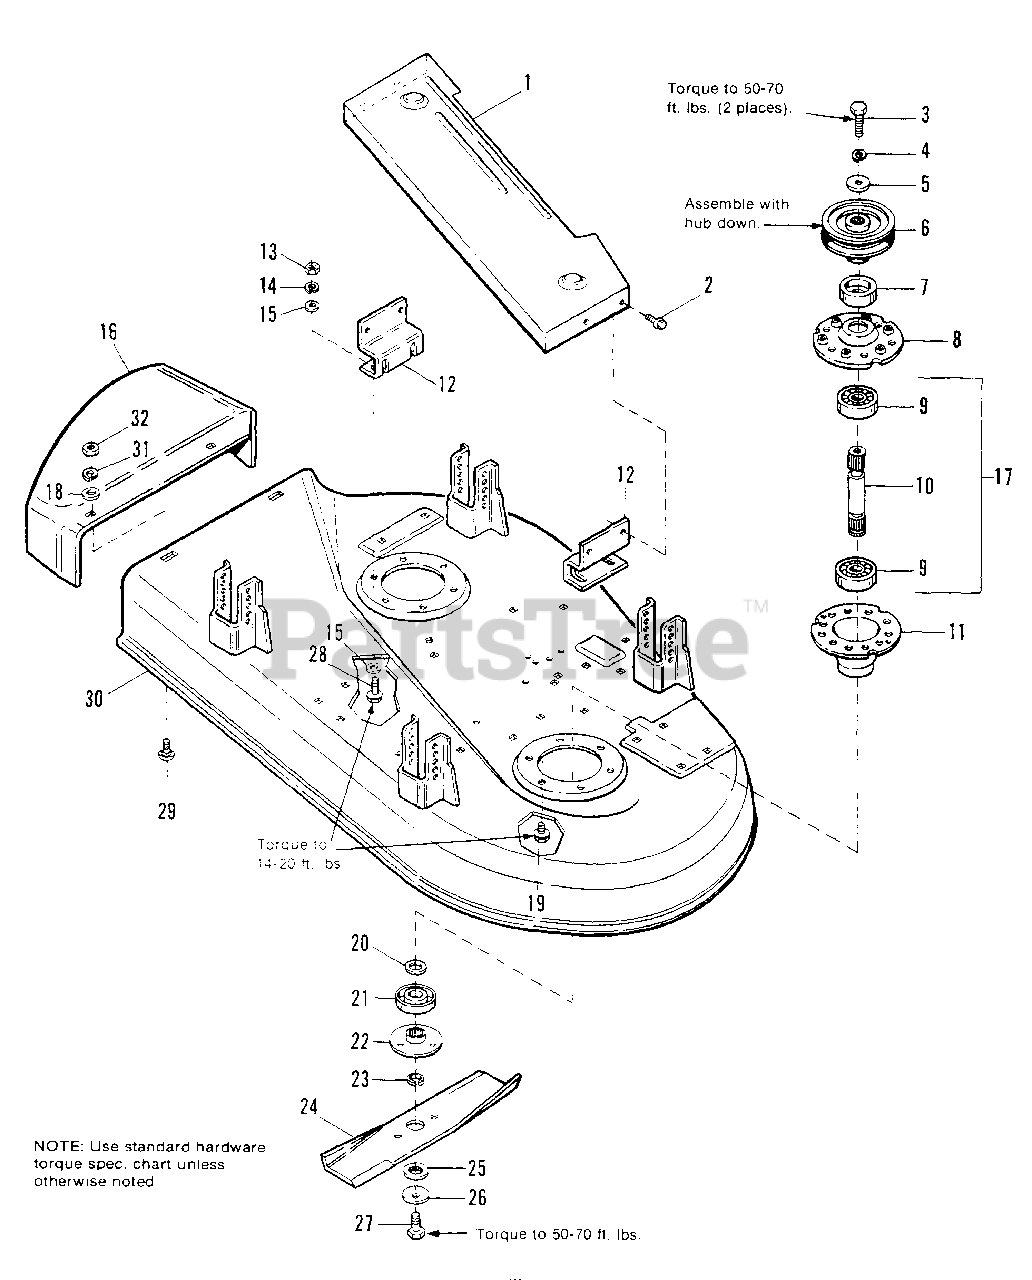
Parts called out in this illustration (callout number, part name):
1	COVER, Belt
2	SCREW, Taptite, 1/4-20 x 3/8
3	CAPSCREW, Hex, 7/16-14 x 1-3/4
4	LOCKWASHER
5	WASHER
6	PULLEY ASSY., Arbor
7	SHIELD, Bearing Upper, Arbor
8	HOUSING, Top
10	SHAFT (Incl. Ref. No. 23)
11	HOUSING, Bottom
12	BRACKET, Belt Cover
13	NUT, Hex, 5/16-18
14	LOCKWASHER, 5/16
15	WASHER, 5/16
16	DEFLECTOR
17	SHAFT & BEARING ASSY. (Incl. Ref. Nos. 9, 10 & 23)
18	WASHER, Plain, 3/8
19	SCREW, Taptite, 5/16-18 x 5/8
21	SHIELD, Lower Grass
22	ADAPTOR, Blade
23	COLLAR, Mower Arbor
25	WASHER, Spline
26	WASHER, Spring
27	CAPSCREW, Hex, 7/16-14 x 1
28	SCREW, Taptite, 5/16-18 x 1
29	CARRIAGE BOLT, 3/8-16 x 3/4
30	HOUSING ASSY., 36" Mower (Incl. Decals)
31	LOCKWASHER, 3/8
32	NUT, Hex, 3/8-16
